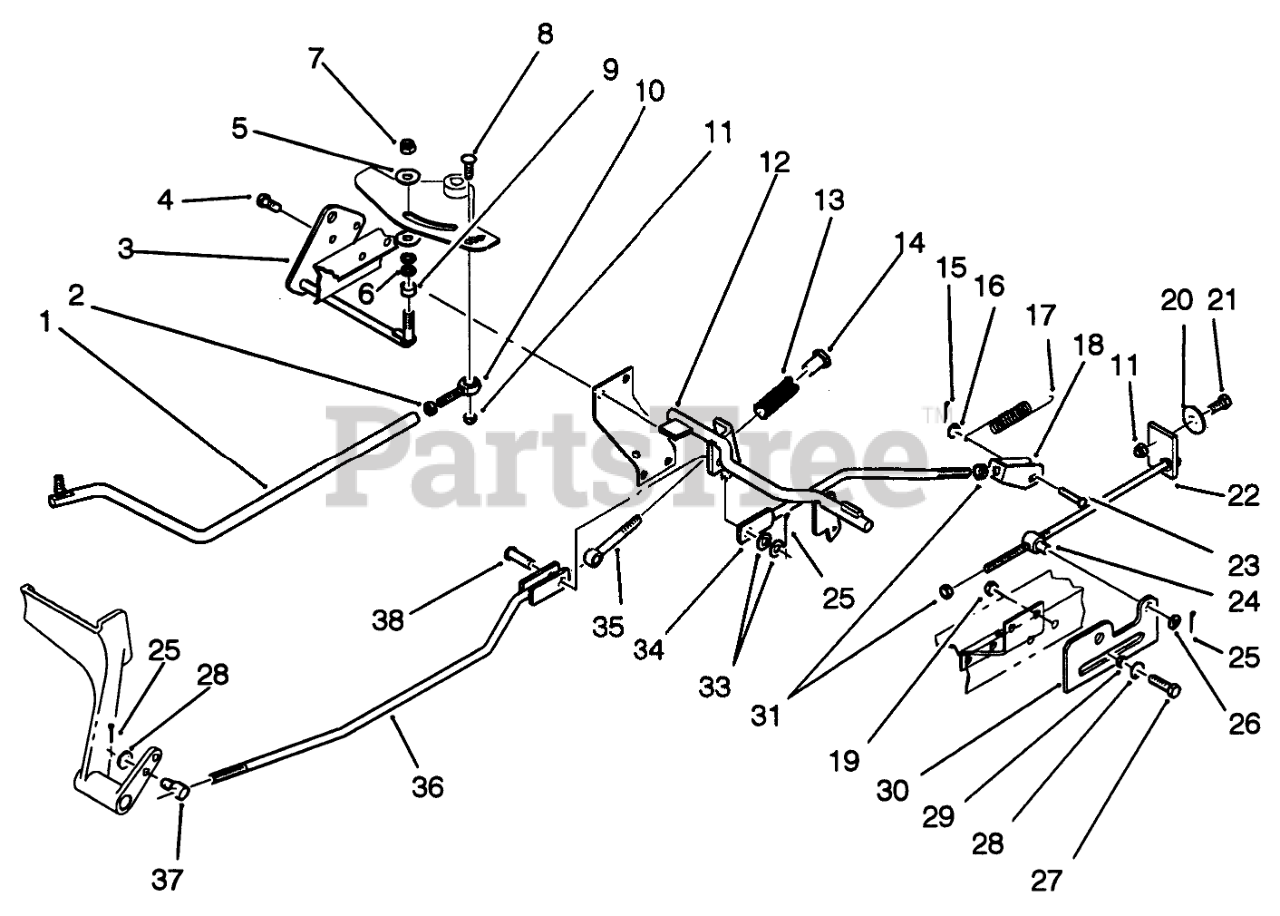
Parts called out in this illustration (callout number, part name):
1	ROD-CONTROL R
2	Nut
3	WLDMT-ROD R
4	Screw
5	FRICTION WASHER
6	WASHER-SPRING DISC
7	NUT
8	Bolt-Carriage
9	SPACER
10	BALL-END
11	NUT-LOCK, NI
12	WLDMT-NEUTRAL SHA R
13	SPRING-COMPRESSION
14	NUT-RETAINER
15	PIN-COTTER
16	WASHER-FLAT
17	SPRING-EXTENSION
18	WLDMT-CLEVIS
20	WASHER
21	SCREW-HH
22	WLDMT-BOLT
23	Pin-Clevis
24	TRUNNION
25	PIN-COTTER
26	WASHER-PLAIN
27	SCREW-HH
28	WASHER-PLAIN
29	SPACER
30	PLATE R
31	NUT-JAM
33	Washer
34	WLDMT-ROD
35	EYE-BOLT
36	WLDMT-BRAKE ROD
36	TRUNNION
38	CLEVIS PIN
